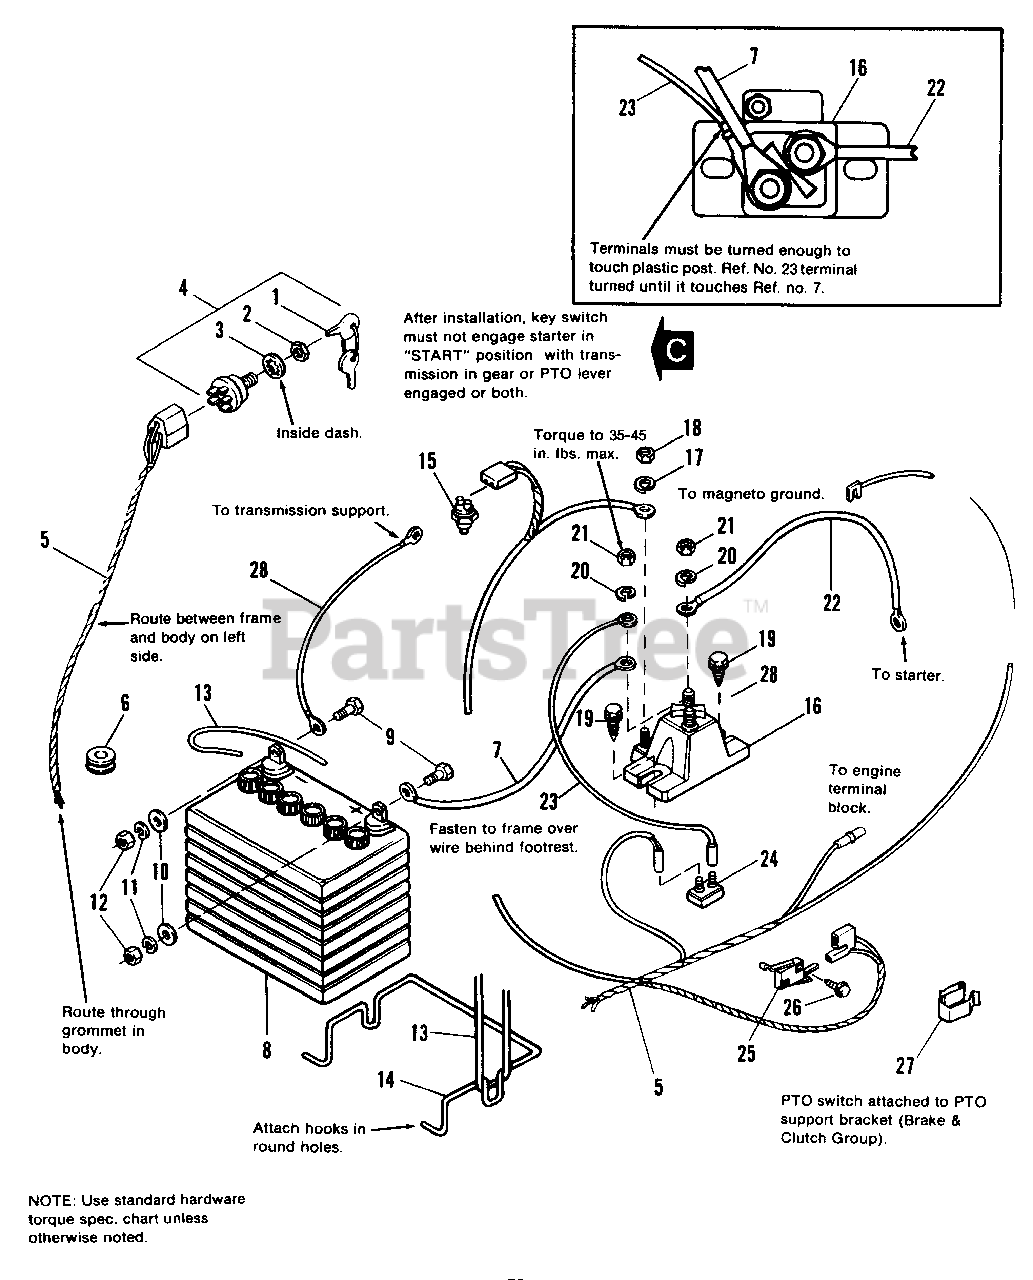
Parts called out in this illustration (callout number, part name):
2	NUT
3	LOCKWASHER, Internal Tooth, 5/8
4	SWITCH, Key
5	HARNESS ASSY.
7	CABLE ASSY. (Batt. to Solenoid)
8	BATTERY, 12 Volt
9	CAPSCREW, Hex, 1/4-20 x 3/4
10	WASHER, Plain, 1/4
11	LOCKWASHER, 1/4
12	NUT, Hex, 1/4-20
13	STRAP, Battery
14	BRACE, Battery
15	SWITCH, Transmission Interlock
16	SOLENOID
17	LOCKWASHER, #10
18	NUT, Hex, Machine, #10-32
19	SCREW, Hex, Taptite, 1/4-20 x 3/4
20	LOCKWASHER, 5/16
21	LOCKNUT, Hex, 5/16-18
22	CABLE ASSY. (Solenoid to Starter)
24	BREAKER, Circuit
25	SWITCH, P.T.O. Interlock
26	SCREW, Hex, Taptite, #50-40 x 3/4
27	CLIP, Tinnerman
28	CABLE (Battery to Ground)
